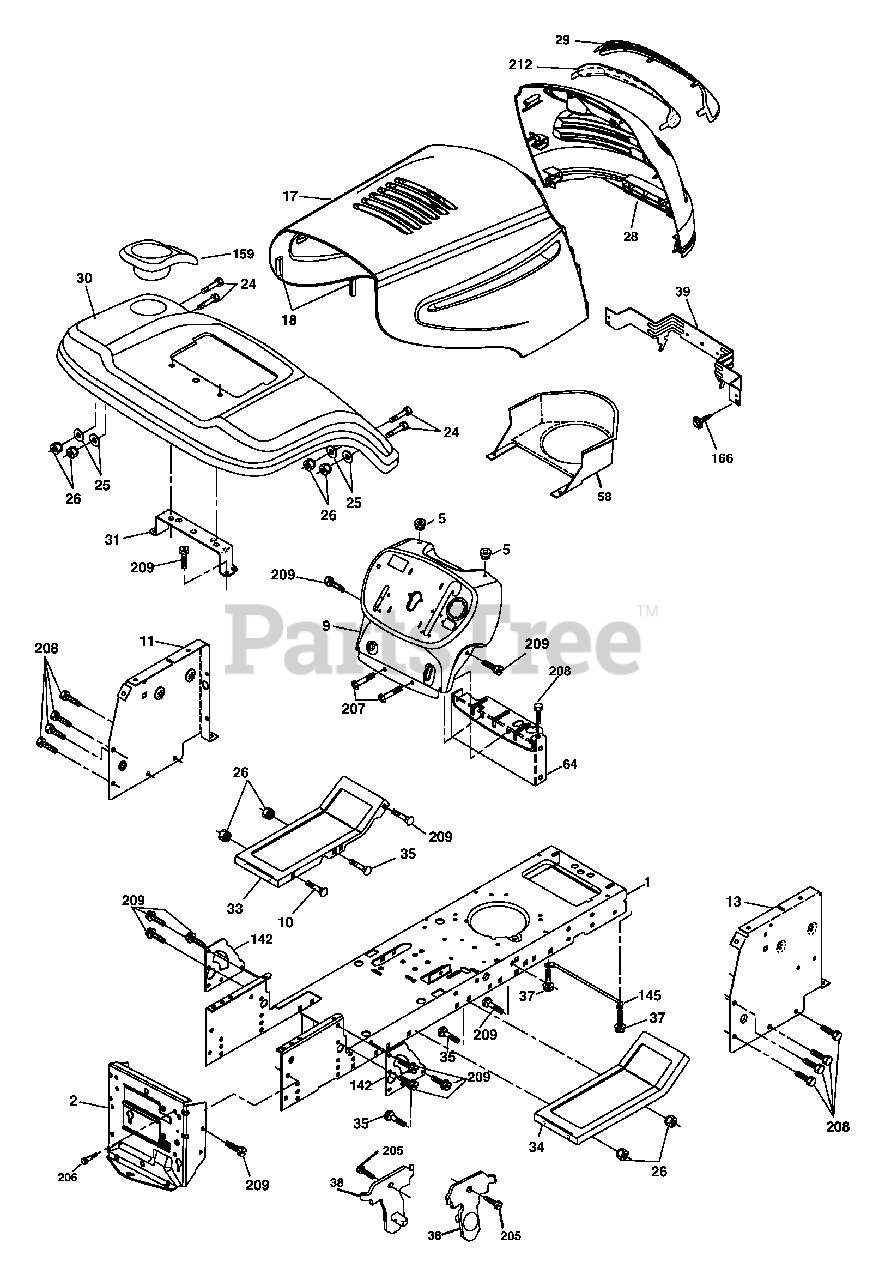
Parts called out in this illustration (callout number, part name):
1	Chassis
2	Drawbar
5	Bumper Hood/Dash
9	Dash
10	Bolt Carriage 3/8-16 x 1
11	Panel Dash Lh
17	Hood
18	Bumper Hood
24	Bolt Fin Hex 3/8-16 x 1 Gr. 5
25	Washer 13/32 x 13/16 x 12 Ga.
26	Nut Lock Hex W/Ins 3/8-16 unc
28	Grille
29	Lens
30	Fender
31	Bracket Support Fender
33	Footrest Pnt Lh
34	Footrest Pnt Rh
35	Bolt Rdhd Sht Sqnk 3/8-16 x 3/4
37	Screw Thdrol 6/16-18 x 1/2 TYT
38	Bracket Asm. Pivot Mower Rear
39	Bracket Pivot
58	Duct Air
64	Dash Lower STLT
142	Plate Reinforcement STLT
145	Rod Pivot Chassis/Hood
159	Cupholder
166	Screw HWHD Hi-Lo #13-16 x 5/8
205	Screw Thdrol 3/8-16 x 1-1/4
206	Bolt Shoulder 5/16-18
207	Screw Thdrol 5/16-18 x 1/2
208	Screw Thdrol 3/8-16 x 1/2
209	Screw Hex Wsh Thdr. 3/8-16 x 3/4
212	Insert Lens Reflect
278	Screw 10 x 3/4 Single Lead-Hex
